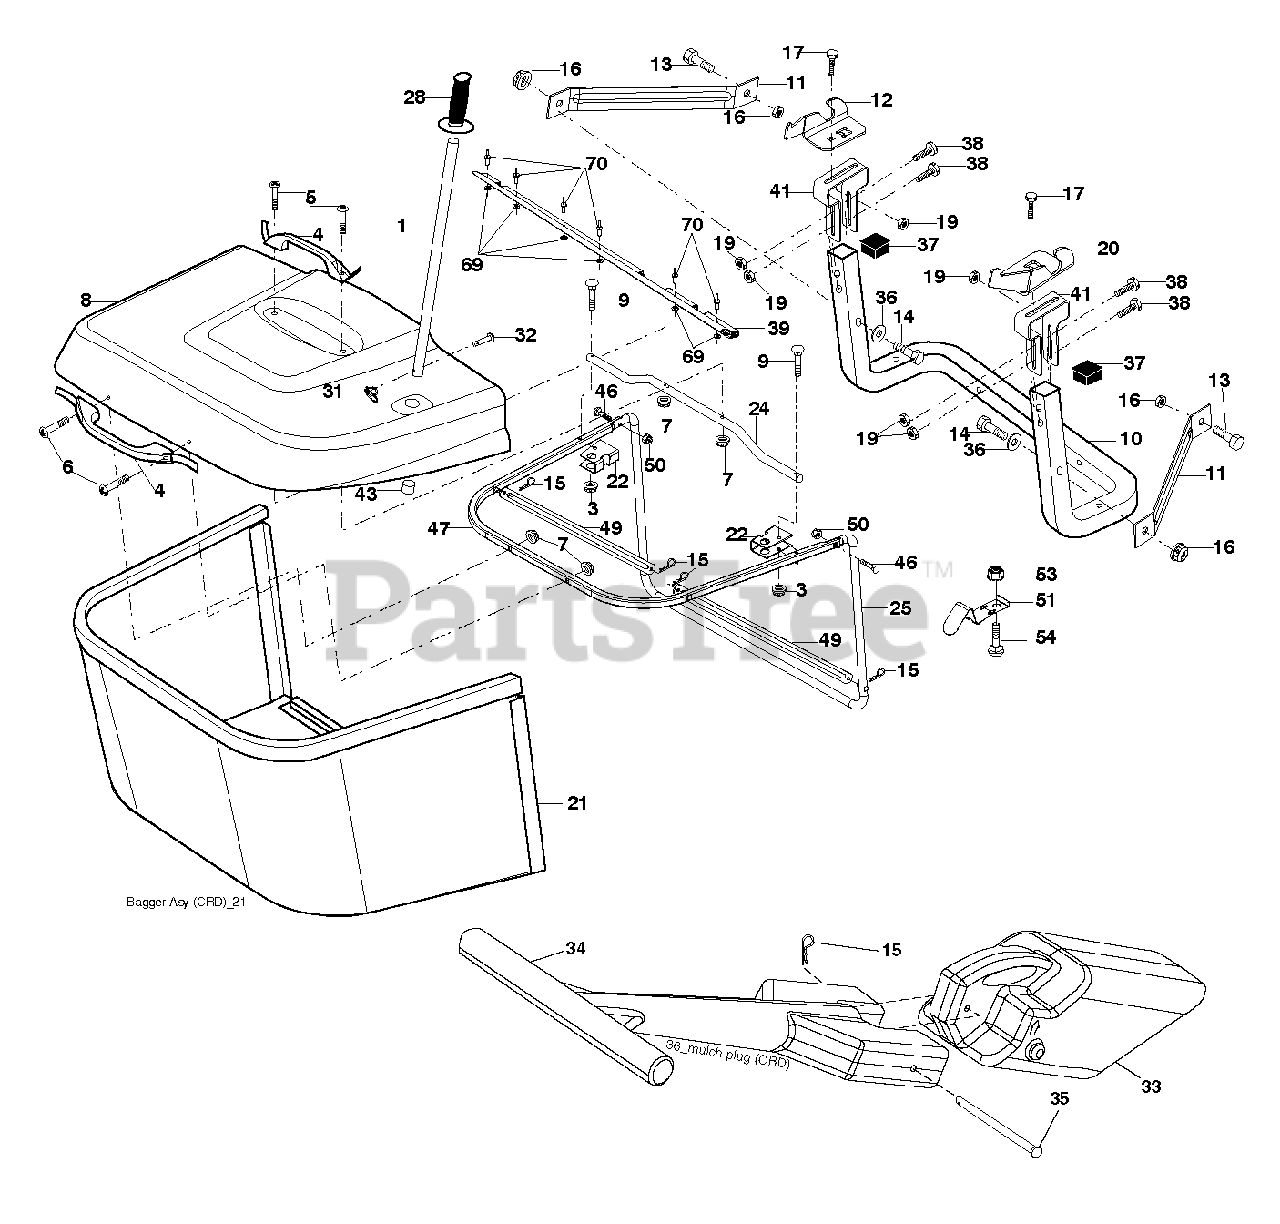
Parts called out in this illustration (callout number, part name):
1	TUBE.HANDLE.BAGGER.CRD/SRD.BLA
3	NUT T
4	HANDLE.BAGGER.W/LVRS.BLK.CRD
5	SCREW.PAN.HEAD
6	REPL BY 532 75 00-29
8	COVER.PNT.BGR.CRD.WSLOTS.MS668
10	TUBE
11	BRACKET.SUPPORT.UPPER.BAG.CRD
12	BRKT PIVOT
14	BOLT-HEX EAK
15	Retainer Spring
16	NUT LOCK FLG 3/8-16 UNC
17	BOLT 5/16-18 X3/4 ZN/YEL GR 5
19	NUT LOCK HEX FLANGE 5/16-18
20	BRKT.PIVOT.RH.CRD
22	BRACKET.BAGGER.SD.ELECTRIC.CRD
24	TUBE.PIVOT.BAG.CRD.BLACK
25	PIPE
28	GRIP.HANDLE.BLACK
31	RETAINER CLIP
32	RIVET,DRILLED
33	MULCHING.PLUG.107.CRD.(2 2)
34	HANDLE.MULCHER.92.CRD (2 2)
36	WASHER
37	PLUG PLUG.SUPPORT.BAGGER.CRD
38	BOLT.5/16-18X2.5
39	SEAL.BAGGER.CRD
41	BRACKET.BAGGER.SD.ELECTRIC.CRD
43	PLUG, TUBING END
46	BOLT.CARRIAGE.5/16-18
47	PIPE
49	ROD
50	NUT.71038.31-18.HEX.NYLOCK
51	LATCH
53	NUT
54	BOLT
69	WASHER
70	RIVET RIVET POP
